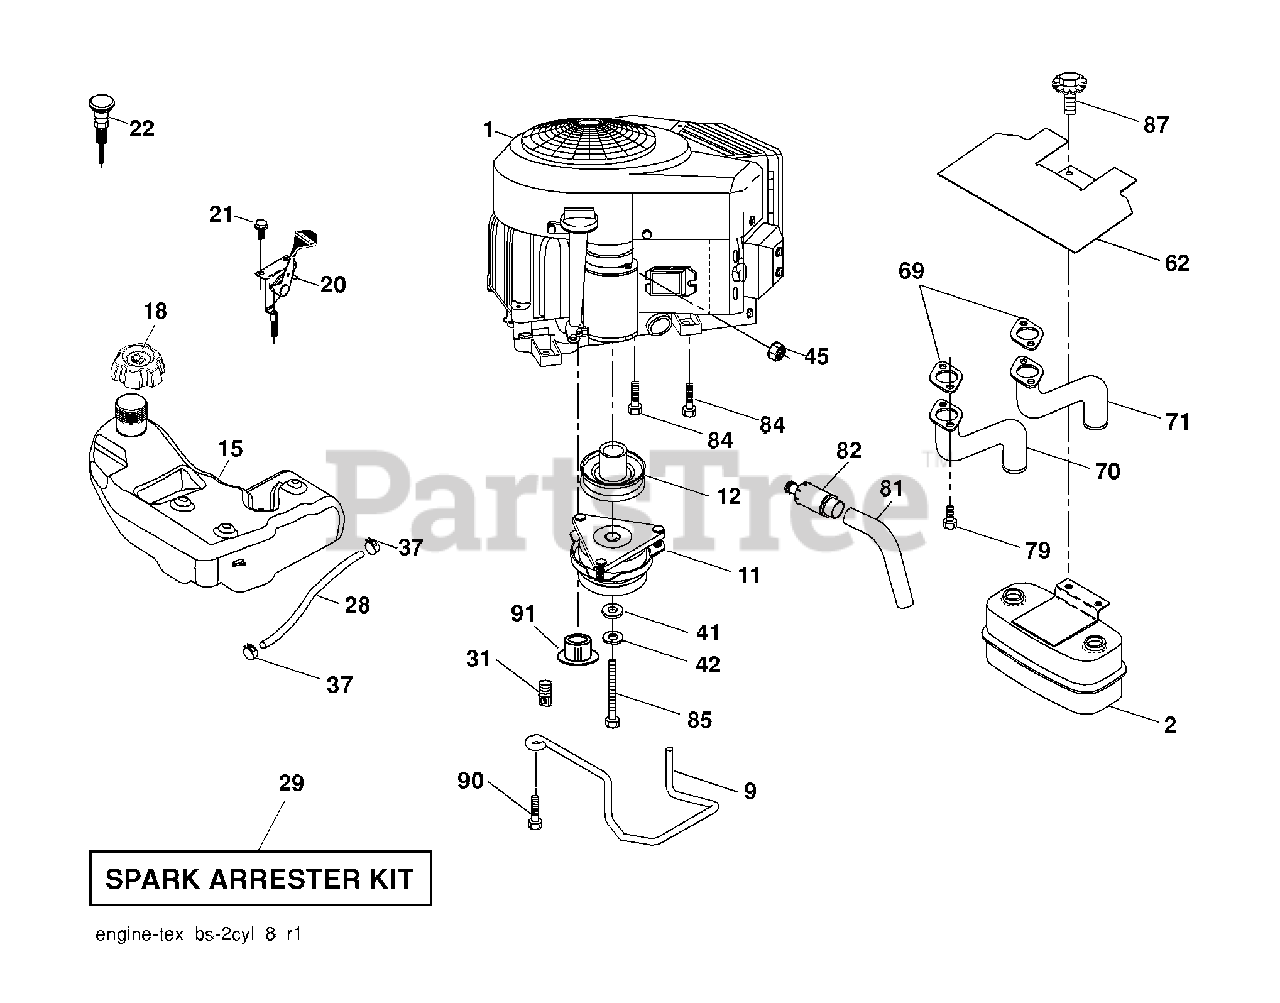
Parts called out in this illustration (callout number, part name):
9	Keeper Belt Engine
11	Clutch Electric
12	Pulley Engine
15	Tank Fuel
18	Cap Asm
20	Control Throttle
21	Screw #10 x 0.750 BOS Thread
22	Control Choke
28	Fuel Line
29	Spark Arrester Kit
31	Clip Push-In
37	Clamp Hose
41	Washer 1-1/2 OD x 15/32 ID x .250
42	Washer Lock 7/16
45	Nut Keps Hex 1/4-20 unc
62	Shield Heat Muffler
70	Tube Exhaust LH
71	Tube Exhaust RH
79	Screw Socket Head 5/16-18 x 1
81	Tube Drain Oil Easy
82	Plug Drain Oil
84	Screw 3/8-16 x 1-1/4
85	Bolt Hex 7/16-20 x 4 Gr. 5
87	Bolt 5/16-18 unc x 1 w/Sems
90	Screw 3/8-16 x 1
